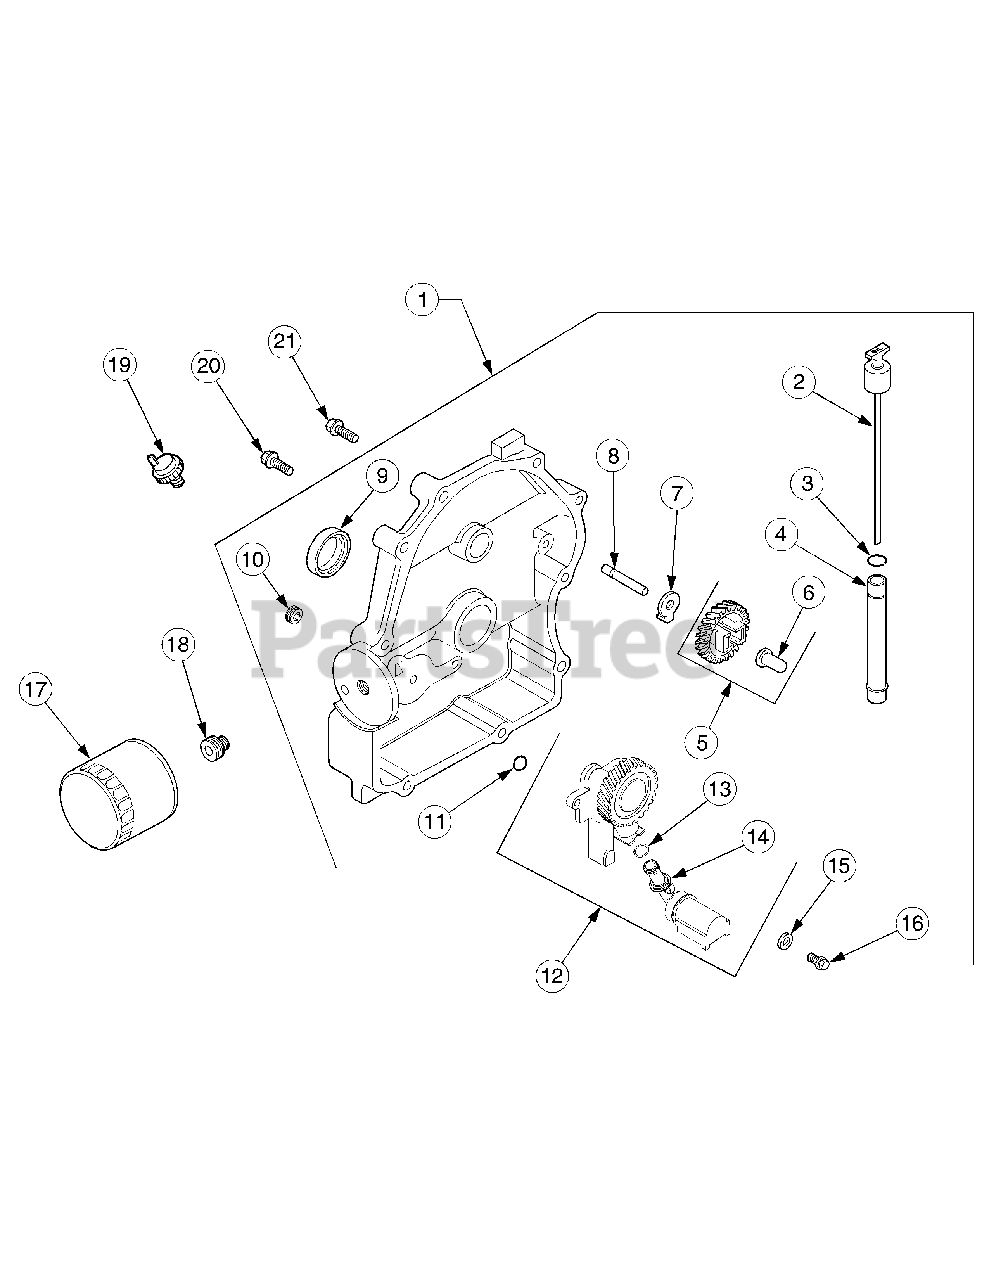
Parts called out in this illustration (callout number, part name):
1	Plate Assy, Closure (Incl. Ref #2-15)
4	Tube, Oil Fill/Dipstick
5	Kit, Governor Gear (Incl. Ref #6)
6	Pin, Governor Regulating
8	Shaft, Governor Gear
9	Seal, Oil (PTO end)
10	Plug, Pipe 1/8
12	Oil Pump Assy (Incl. Ref #13-14)
13	O-Ring, Oil Pick-up
14	Pick-up, Oil
15	Washer, Plain
16	Screw, Hex Flange, M6 x 1.0 x 25
17	Filter, Oil
18	Nipple, Oil Filter
19	Switch, Pressure
20	Screw, Hex Flange, M8 x 1.25 x 45
21	Screw, Hex Flange, M8 x 1.25 x 45
